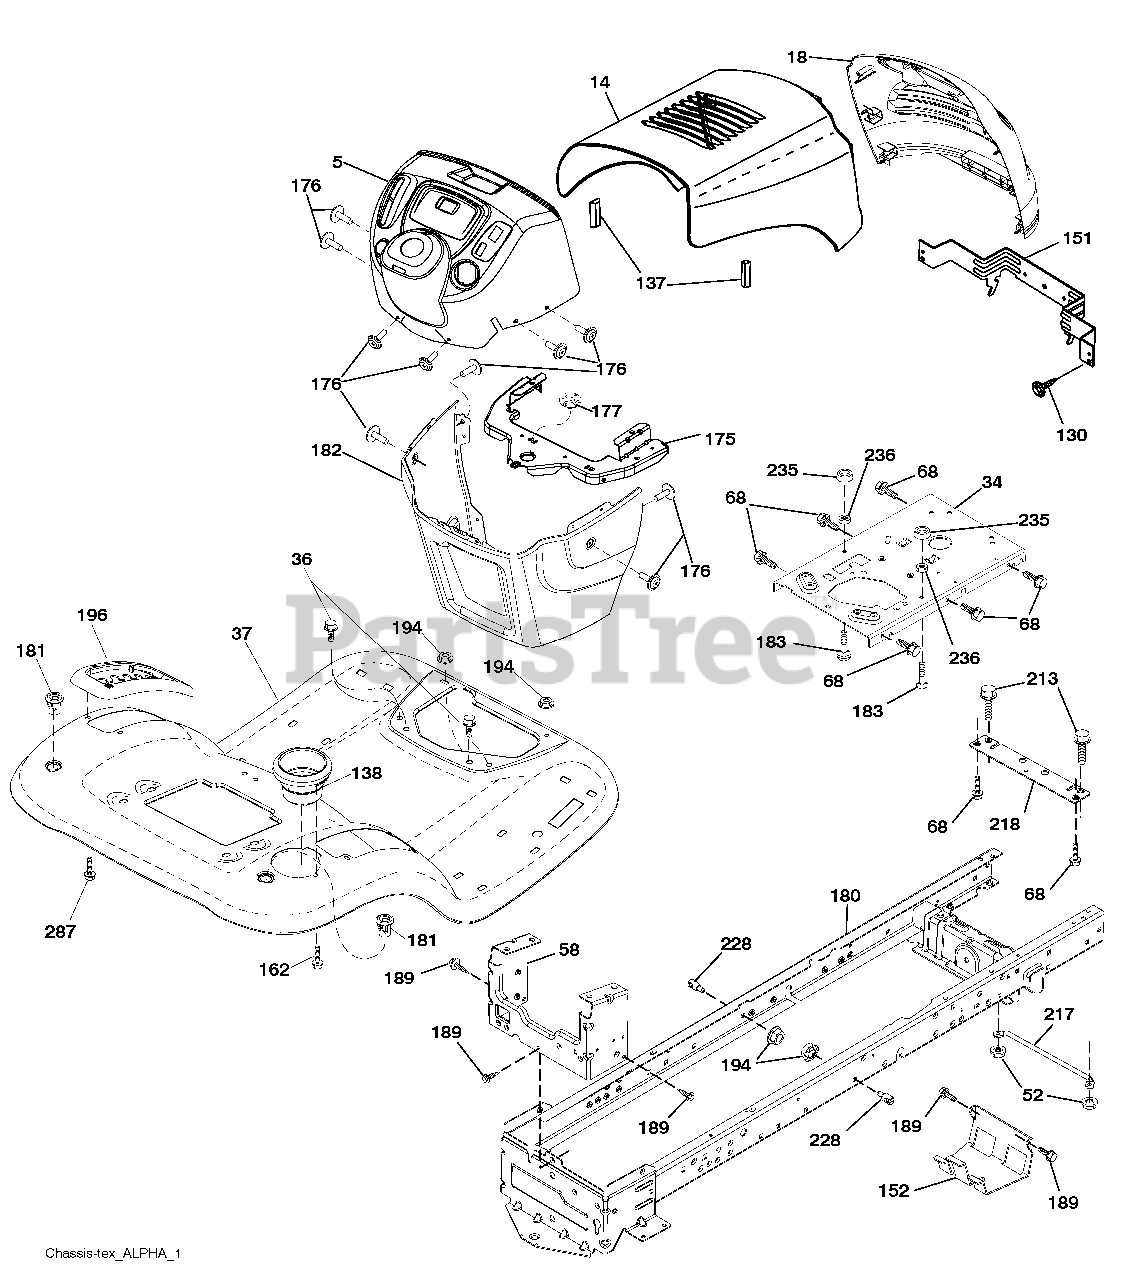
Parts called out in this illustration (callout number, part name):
5	Dash
14	Hood
18	Grille
34	Plate Engine
36	Screw 5/16-18 x 3/4
37	Fender
52	Nut Lock 5/16-18
58	Drawbar Upper
68	Screw Thdrol 5/16-18 x 1/2
130	Screw #10 x 0.750
137	Bumper Hood
138	Cupholder
151	Bracket Pivot
152	Shield Browning/Debris
162	Screw Hex Wsh Hi-Lo 1/4 x 1/2
175	Crossmember
176	Screw 10-24 x 5/8 Wshd Qdrx
177	Bushing Steering
181	Bushing Mtg. Fender Crgo.
182	Dash Lower
183	Bolt 5/16-18 x 1-1/4
189	Screw 5/16-18 x 3/4
194	Nut Lock Hex Flange 5/16-18
196	Console Asm. Deck Lift
213	Bolt 5/16-18 x 3/4
217	Rod Pivot Hood
218	X-Piece Hood Stop
228	Stud Fastener
235	Spacer Fender
236	Nut Center Lock 5/16-18
287	Screw 1/4-20 x 3/8
287	Plug Switch Light
